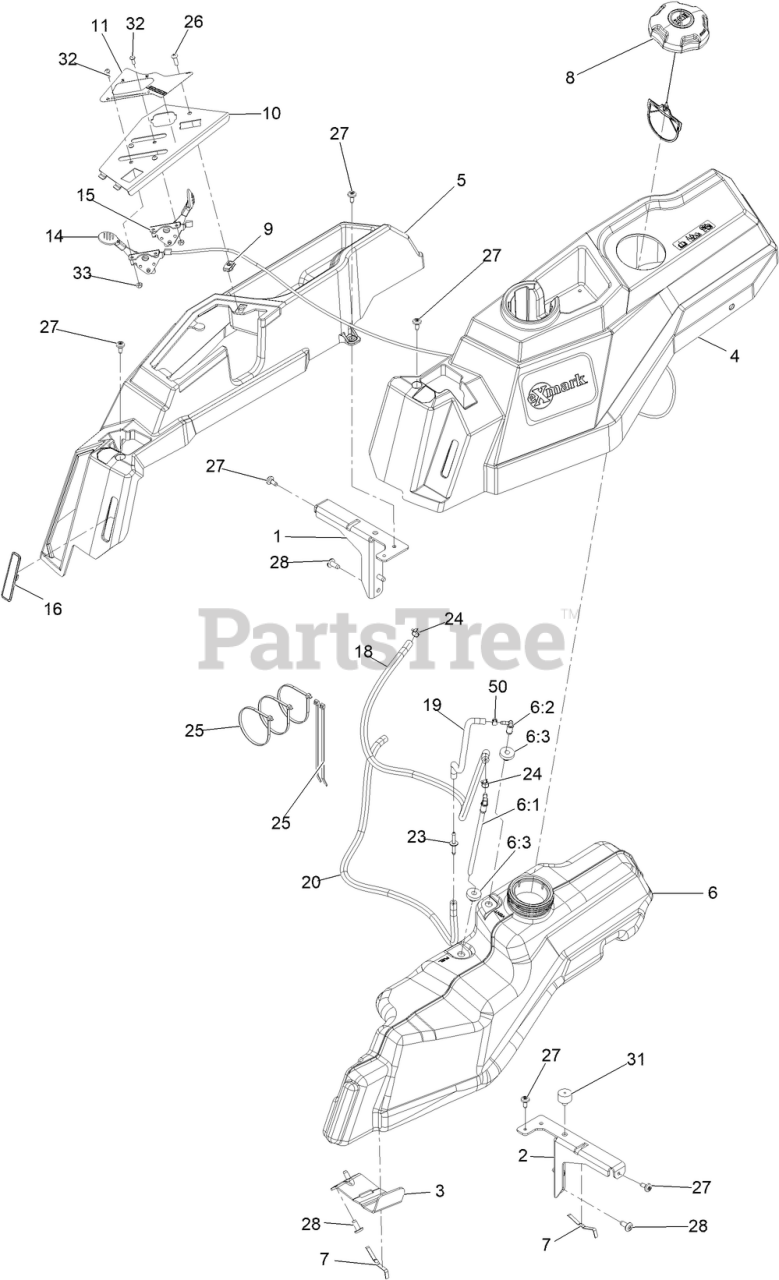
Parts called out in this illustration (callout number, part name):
1	SUPPORT-POD, RH
2	SUPPORT-POD, LH
3	SUPPORT-TANK, FUEL
4	POD- LH
5	POD- RH
6	TANK-FUEL ASM
6:1	Connector-Elbow, 90 DEG
6:2	Fitting-Elbow 90
6:3	BUSHING
7	SPRING
8	CAP-FUEL, RATCHETING
10	PANEL- CONTROL
11	DECAL-CONTROL PANEL
14	ASM,THROTTLE CABLE
15	CABLE-CONTROL, CHOKE
16	PLUG-SC
18	HOSE-FUEL
19	Hose-Fuel
20	Hose, Fuel
23	Adapter Orifice
24	CLAMP-HOSE
25	TIE-CABLE
26	SCREW-PRH
27	SCREW-SHOULDER
31	BUMPER-GROMMET
32	SCREW-PPH
33	NUT-LOCK, NI
50	CLAMP-HOSE
